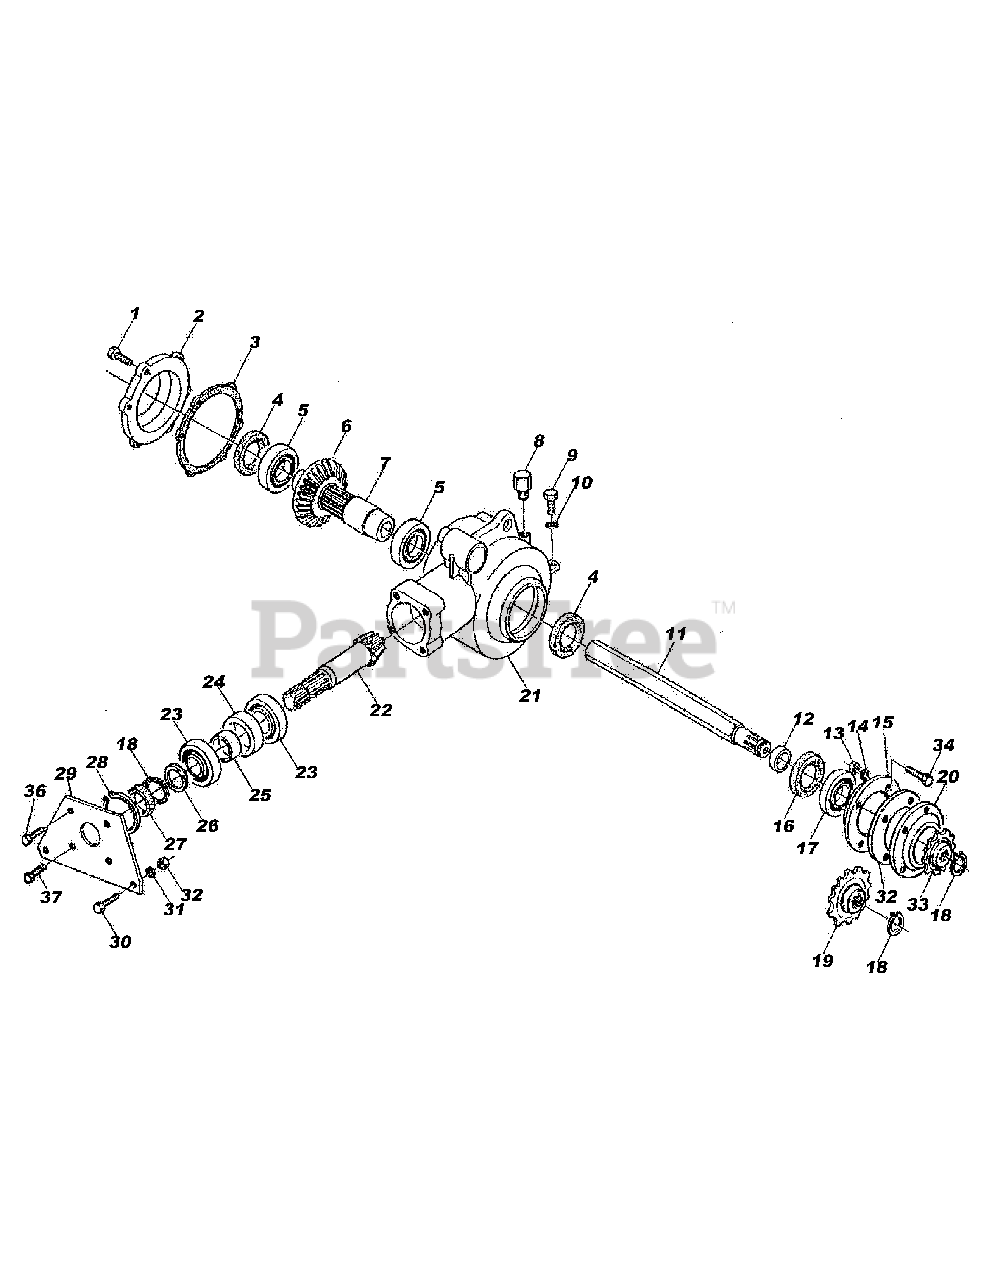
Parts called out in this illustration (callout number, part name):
1	Bolt 10 x 20
2	Gear Cover
3	Gasket
4	Oil Seal 50.68.10
5	Bearing 6010
6	Bevel Gear
7	Shaft Coupling
8	Breather Cap
9	Bolt M12 x 40
10	Lock Washer M12
11	Hexagonal Shaft
12	Spacer
13	Nut M10
14	Lock Washer M10
15	Bearing Cover Inner
16	Oil Seal 45.60.10
17	Bearing 6307
18	Snap Ring M35 Ext.
19	Sprocket Z14 Standard
20	Bearing Cover Outer
21	Gear Box Housing Cast
22	Pinion Gear
23	Bearing 6207
24	Spacer - Rear Outer
25	Spacer - Rear Inner
26	Spacer - Ring
27	Oil Seal 35.72.10
28	Snap Ring 72 Inner
29	Metal Cover
30	Bolt M12 x 35
31	Lock Washer 12mm
32	Nut 12mm
33	Sprocket Z11
34	Bolt M10 x 30
35	Disk with Holes
36	Bolt M10 x 35
37	Bolt M10 x 30
